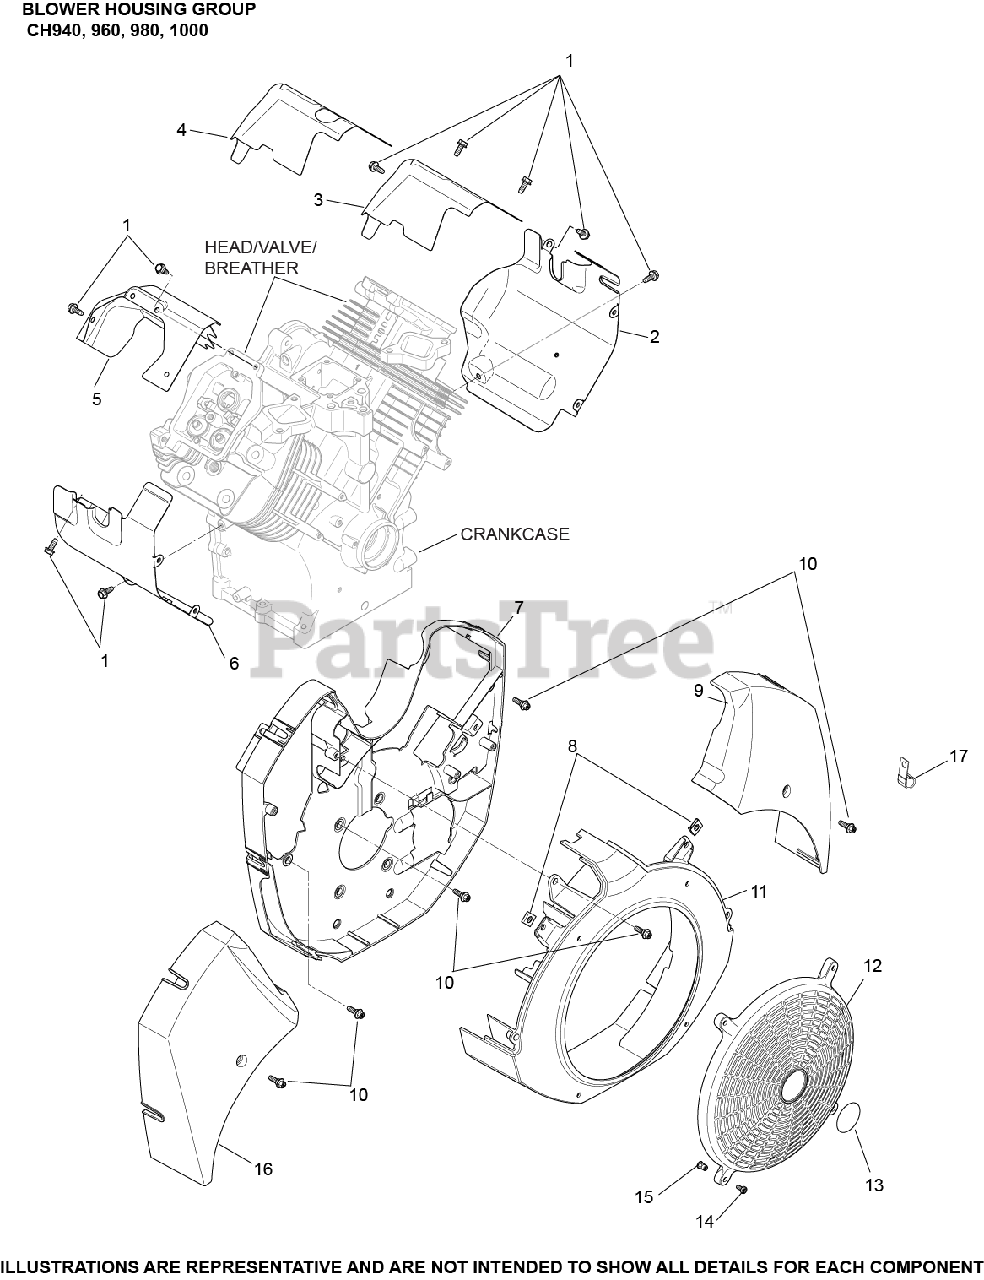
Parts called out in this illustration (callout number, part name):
1	SCREW, THREAD FORMING
2	BAFFLE, CYL BARREL #1 SIDE
3	BAFFLE, VALLEY #1 SIDE
5	BAFFLE VALLEY #2 SIDE
6	BAFFLE CYL BARREL #2 SIDE
7	SHROUD, BACKING-USE 62 424 15-S
8	CLIP, BAFFLE MOUNTING USE 25 154 37-S
9	SHROUD, #1 CYLINDER
10	SCREW, SHD THD FRM
11	HOUSING, BLOWER - (#6202707S)
12	KIT, FIXED GUARD
13	DECAL, GRASS SCREEN
14	SCREW, LBD SCKT PAN M5X0.8X10
15	INSERT, THREADED
16	SHROUD, #2 CYLINDER
